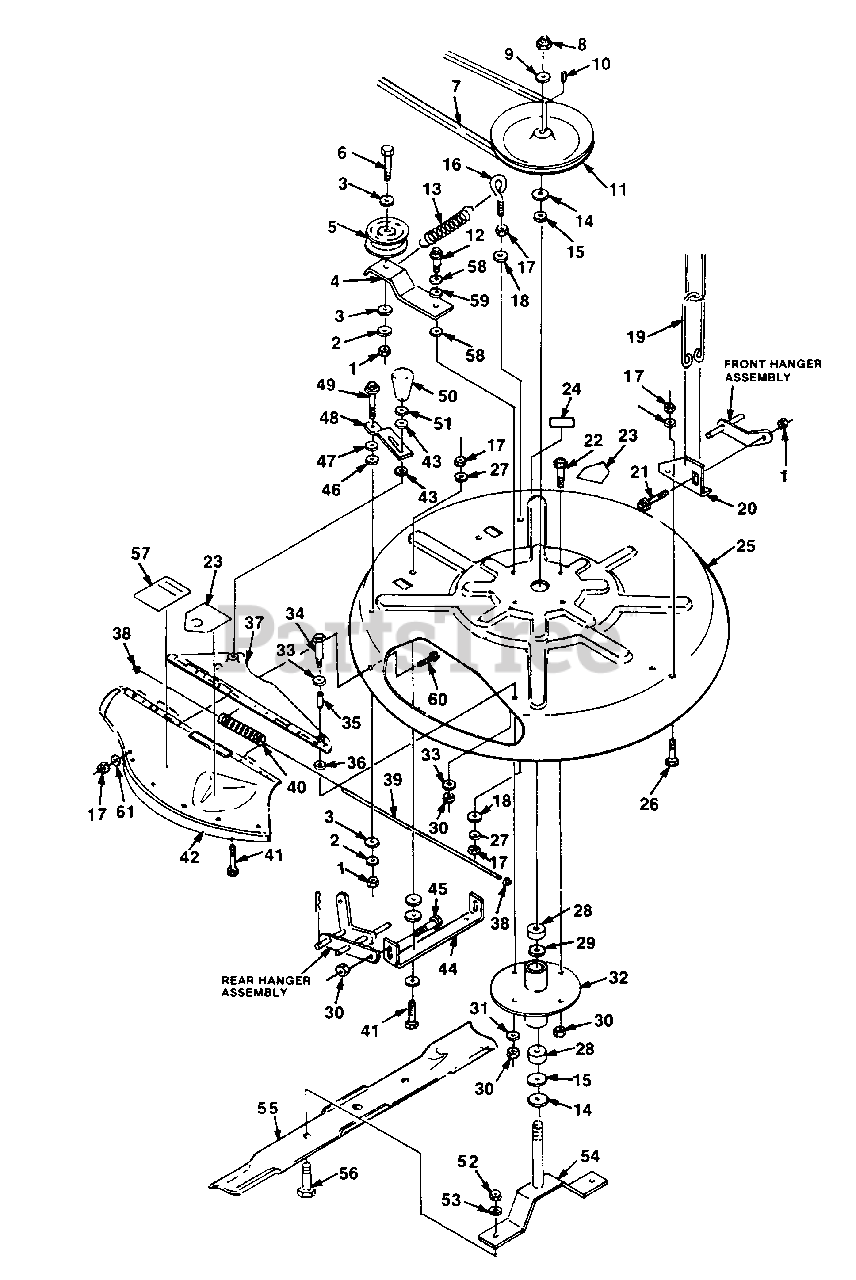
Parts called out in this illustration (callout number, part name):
1	NUT- Hex-centerlock 3/8-16
2	WASHER- Lock 3/8
3	WASHER- Flat 7/16
4	ARM- Pivot
5	PULLEY- Idler
6	SCREW- Cap - hex hd 3/8-16 x 1.750
8	NUT- Hex locking
9	WASHER- Flat 13/16
10	KEY- 3/16 x 1.00
11	PULLEY- Spindle
12	SCREW- Cap-hex hd 5/16-18 x 1.250
13	SPRING- Extension
14	SPACER .10O Thick
15	WASHER .036 Thick
16	BOLT- Eye
17	NUT- Hex-centerlock 1/4-20
18	WASHER- Flat 1/4
19	LINK- Lower front lift
20	BRACKET- Front lift
21	BOLT- Shoulder 3/8-16 x 2.125
22	SCREW- Cap-hex hd 5/16-18 x 6.25
23	DECAL- CPSC Warning
24	DECAL- No step
25	DECK-Cutter 30"
26	SCREW- Cap-hex hd 1/4-20 x .625
27	WASHER- Lock 1/4
28	BEARING- Cutter shaft
29	SPACER- Bearing
30	NUT- Hex centerlock 5/16-18
31	WASHER- Lock 5/16
32	SPINDLE HOUSING
33	WASHER- 5/16 SAE
34	SCREW- Hex hd. cap 5/16-18 x 1
36	WASHER- Flat 3/8
37	PLATE- Discharge
39	ROD- Deck hinge
40	SPRING- Torsion
41	SCREW- Cap - hex hd 1/4 x 20 x .750
42	COVER- Discharge
43	WASHER- Lock 1/4 hvy
44	BRACKET- Rear lift
45	BOLT- Shoulder 5/16 x 18
46	WASHER- Flat 17/32
47	WASHER- Spring
48	ARM- Pivot
49	BOLT- Hex hd cap 1/4-20 x .625
51	WASHER- Lock Med 1/4
52	NUT- Hex centerlock 1/2-13
53	WASHER- Lock 1/2
54	SPINDLE & ADAPTER
55	BLADE
56	SCREW- Cap hex hd 1/2-13 x 1 25
57	DECAL- Danger
58	WASHER- Idler arm
59	SPACER- Idler arm
60	SCREW-1/4-20 x 1"
61	WASHER-Flat 1/4"
